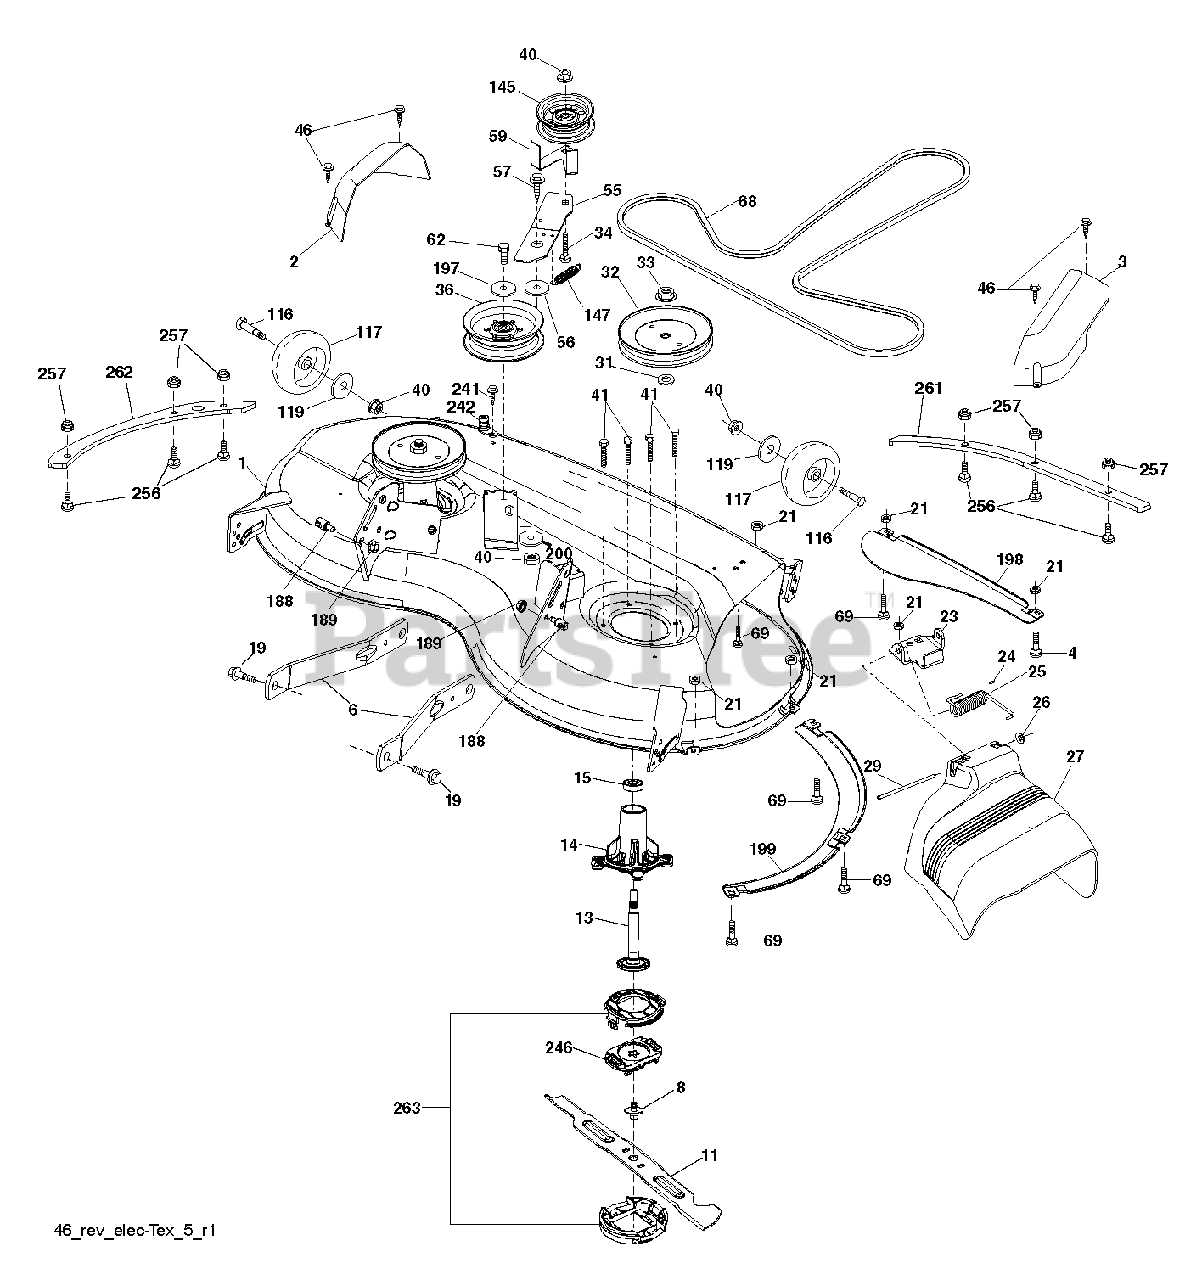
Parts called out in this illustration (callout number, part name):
1	DECK SVC 46"417585X668
2	COVER.MANDREL.LH.46"
3	COVER.MANDREL.RH.46"
4	BOLT
6	ARM.SUSPENSION.MOWER.R
8	SCREW.SEMS.7/16-20X1.HEX.HEAD
11	BLADE.REVOLTION.46"BAGER.PT43
13	SHAFT ASM.REV.TALL.N/GREASEBL
14	HOUSING.MANDREL.REV.TALL.N/GRS
19	BOLT.SHOULDER
21	LOCKNUT
23	BRKT.DEFLECTOR.38"2005+
24	CAP-SLEEVE LT
25	SPRING.TORSION.DEFLECT
26	NUT PUSH M
27	SHIELD.DEFLECTOR.MOWER.46"BLAC
29	ROD.HINGE
31	WASHER.SPACER.MANDREL
32	PULLEY.MANDREL.5.438.PD
33	NUT.FLANGE.LOCK.TOP
34	BOLT.3/8-16X1.50
36	PULLEY.IDLER.2006
40	NUT LOCK FLG 3/8-16 UNC
41	BOLT.HEX.WASHR.HED.313-18X1.19
46	SCREW.1/4-20X5/8
56	SPACER.RETAINER
57	SCREW 3/8-16X1
59	GUARD, BELT
62	BOLT-HEX EAK
68	V-BELT
69	BOLT
116	BOLT.SHOULDER.3/8-16X3-5/8.
117	WHEEL. GUAGE RALLY
119	WASHER
145	PULLEY.IDLER.48"PRIMARY
147	SPRING.MOWER.DRIVE.ELECTRIC
188	STUD.FASTNER.W/ANTI-ROTATE
189	NUT LOCK HEX FLANGE 5/16-18
197	WASHER
198	BAFFLE CENTER FRONT
199	BAFFLE FRONT RH
200	WASHER.13/32 X 1 X 1/2.11GUARD
241	SCREW.TT.#10-32X.5.3/8.FLANGE
242	PORT.WASHOUT
246	HOLDER.BLADE.REVOLUTION
256	SCREW.BUTTONHEAD.1/4-20X1
257	NUT T
261	PLATE.REINFORCE.46.BOLT.ONX431
262	PLATE.REINFOR.46.SIDEBOLT.X431
263	CAP.REVOLUTION ASM
